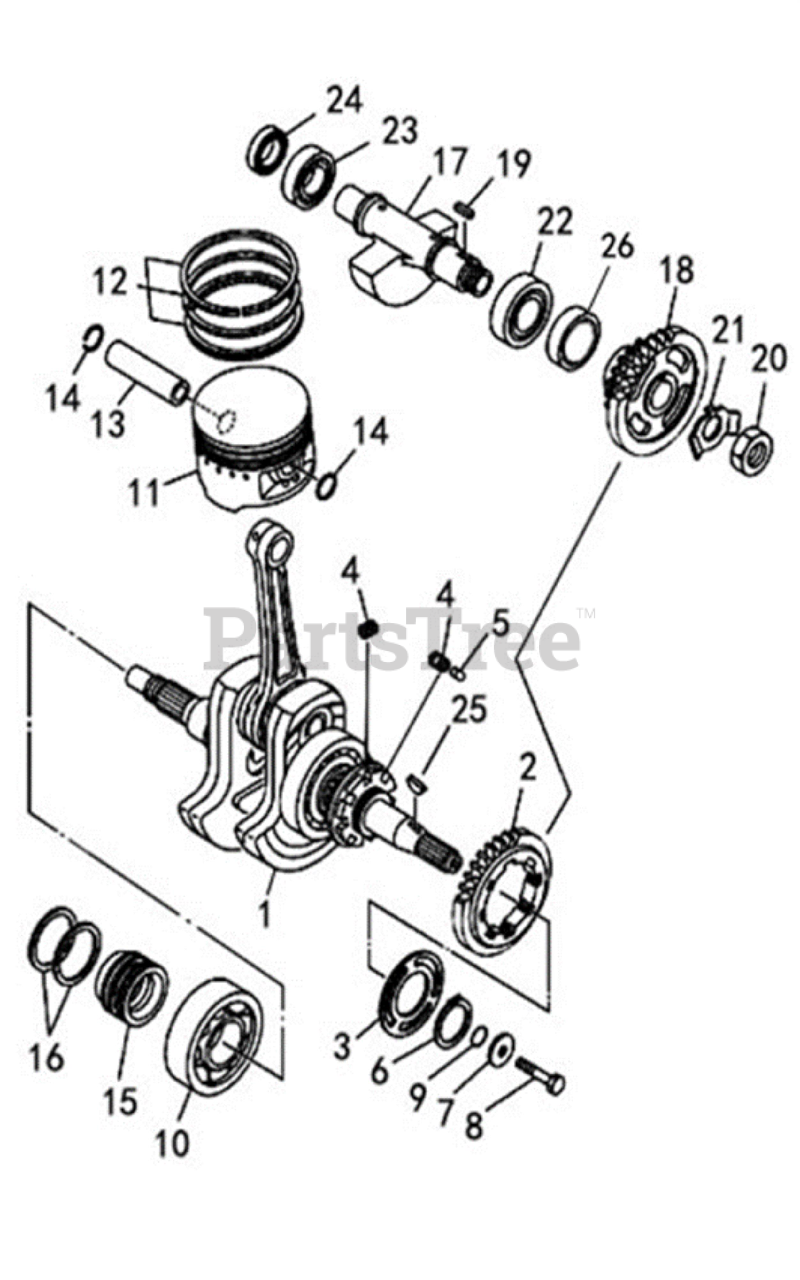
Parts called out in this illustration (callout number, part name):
1	Crankshaft Assy
2	Driving Gear,Balance Shaft
3	Locating Plate,Balance Gear,Outer
4	Buffer Spring,Balance Gear
5	Washer Pin,Balance Gear
6	Circlip for shaft 35
7	Washer 10X32X5
8	Hexagon Head Bolts M10X1.25X40
9	O-Ring 16X3
10	Bearing 6307
12	Piston Ring Set
13	Piston Pin
14	Circlip,Piston Pin
15	Bushing,Sealing Ring
16	Sealing Ring
17	Balance Shaft assy
18	Balance driven gear assy
20	Hexagon Nut M18X1
21	Tab Washer A
22	Bearing 6305
23	Bearing 6304
24	Oil Seal 20X30X7
25	Key
26	Bushing,Balance driven gear
